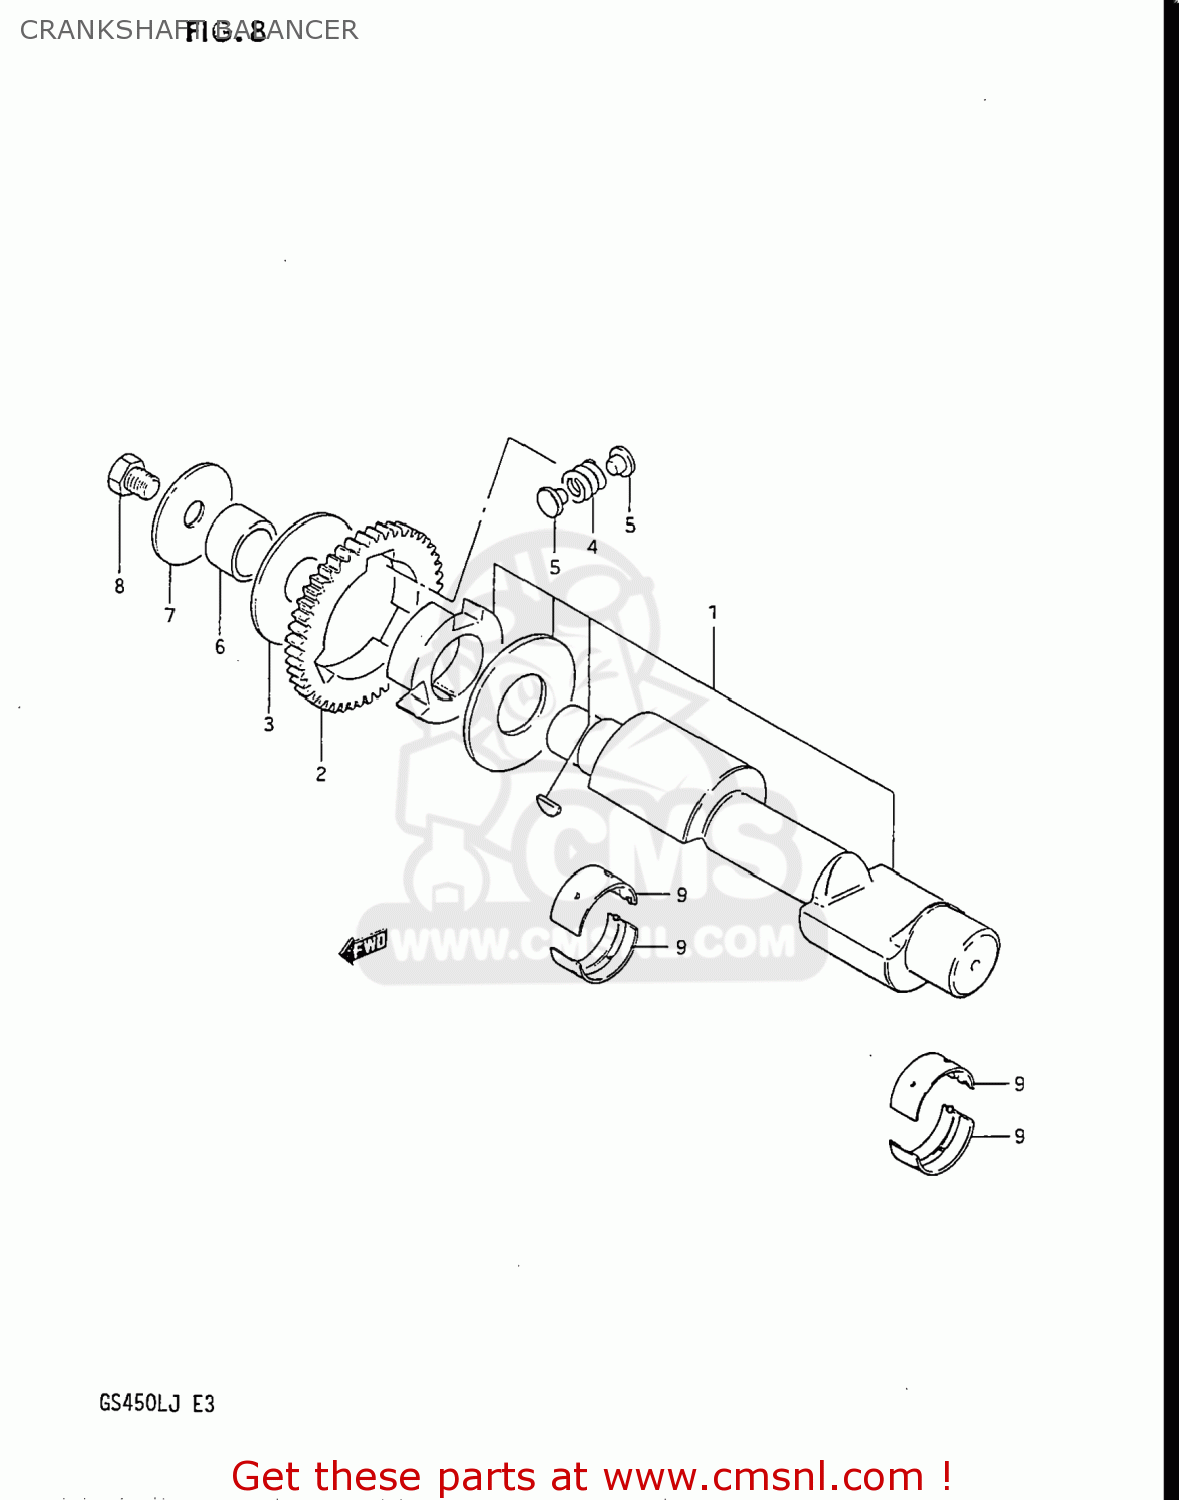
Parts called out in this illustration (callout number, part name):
1	BALANCER,CRANKSHAFT
2	GEAR,CRANK BALANCER DRIVE
3	WASHER
4	SPRING
5	PIN
6	SPACER
7	WASHER(12X50X3)
8	BOLT
9	METAL CRANKSHAFT
